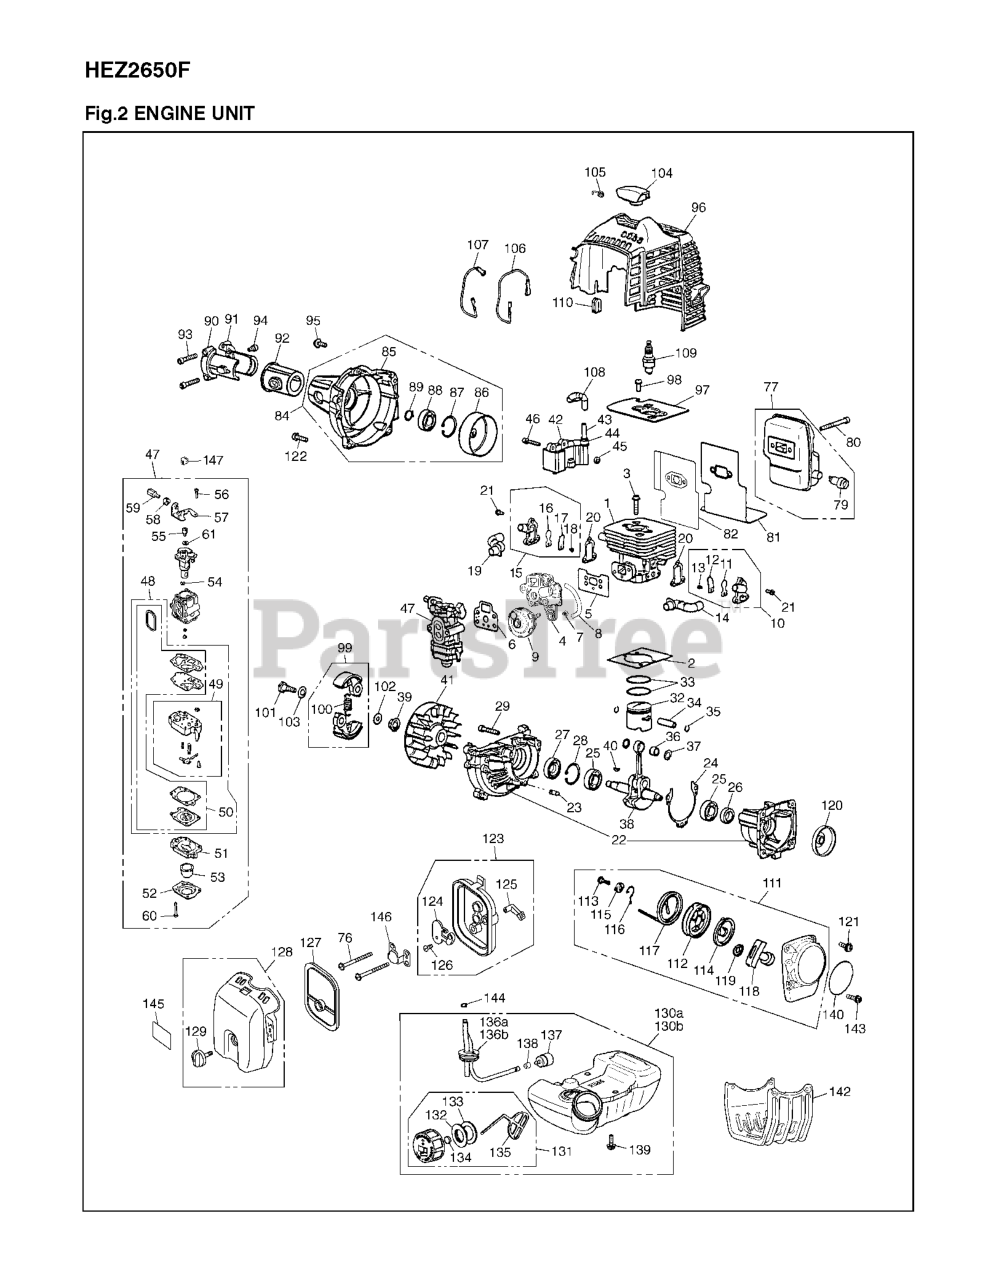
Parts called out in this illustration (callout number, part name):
1	CYLINDER
2	GASKET, BASE
3	BOLT
4	INSULATOR
5	GASKET, INSULATOR
6	GASKET, CARB (RPLS T155113131)
9	PUMP ASSY
10	AIR CHECKER (S) ASSY
11	REEDVALVE
14	PIPE AIR (S)
15	AIR CHECKER (F) ASSY
16	REEDVALVE
19	PIPE AIR (F)
20	GASKET, VALVE
21	BOLT
22	CRANKCASE-C
23	PIN
24	GASKET.CASE
27	SEAL
34	PIN (RPLS T151341310)
38	CRANKSHAFT COMP(RPLS481042000)
39	NUT
40	KEY
44	CAP
45	SPACER
47	CARBURETOR ASSY
48	REBUILD KIT
49	CARBURETOR BODY
50	GASKET KIT
51	BODY CARB
52	1OVER
54	RING
55	SWIVEL
56	SCREW
57	BRACKET
58	NUT
59	ADJUSTER
61	WASHER
79	ARRESTER
82	PLATE, MUFFLER
84	COVER-C
85	COVER.FAN
90	BRACKET(A)-24
91	BRACKET(B)-24
96	COVER, ENGINE
107	CORD.EARTH
108	TUBE (RPLS 263072210)
109	PLUG CMR7H
111	RECOIL-A
114	SPRING, SPIRAL
115	COLLAR
116	SWING ARM
119	PLATE.STOPPER
122	BOLT
123	BODY, CLEANER
124	PLATE, CHOKE
126	SCREW
127	ELEMENT
128	COVER ASSY
129	Cleaner Knob
130	TANK ASSY
132	HOLDER-A
136	PIPE-C
136	PIPE COMP
137	FILTER
138	CLIP
140	LABEL, RECOIL
144	CLIP
